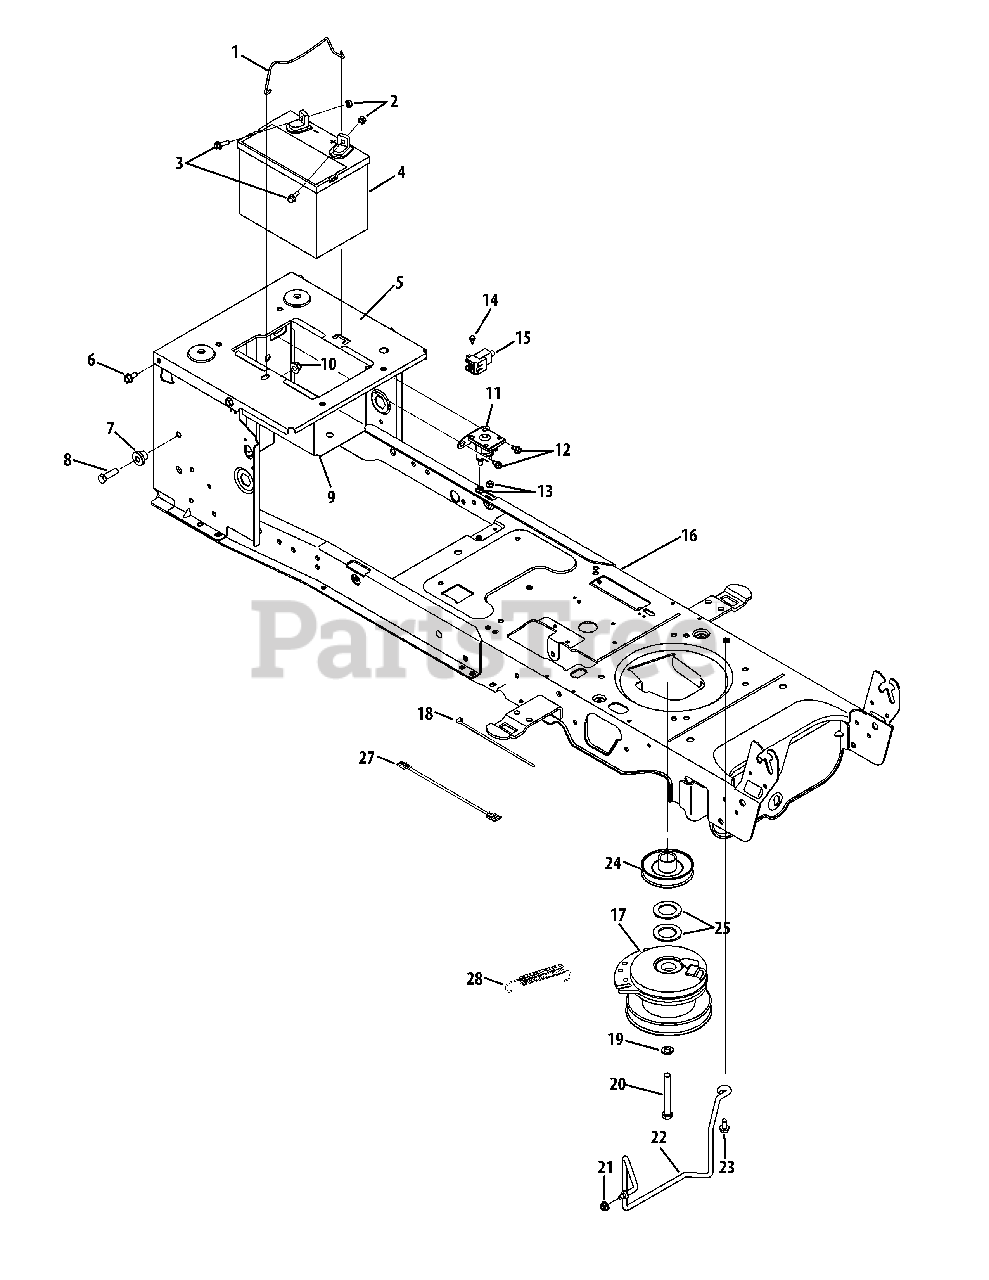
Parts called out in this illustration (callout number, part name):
1	Battery Hold Down Rod
2	Sems Hex Nut 1/4-20
3	Hex Hd. Flg. Scr. 1/4-20 x .75 Gr. 5
4	Battery
5	Seat Frame Bracket
6	SCREW 5/16-18 x .750
7	Shoulder Spacer .38 x 1.0 x .70
8	Hex Bolt 3/8-16 x 1.25
9	Battery Tray
10	Flange Lock-Nut 3/8-16 Gr. F Ny lon
11	Solenoid
12	Hex Wash HD Tapp Scr 1/4-20 x .375
13	Hex L-Flanged Nut 1/4-20 Gr. F Nylon
14	Shoulder Screw #10-32 x .50
15	Switch, Interlock
16	Lower Frame Ass'y
17	Electric PTO Clutch (50" deck)
17	Electric PTO Clutch (54" deck)
18	Cable Tie
19	Flat Washer .450 x 1.25 x .164
20	Hex Screw 7/16-20 x 3.5 Gr. 5
21	Flange Locknut 5/16-18 Gr. F, Nylon
22	Keeper Rod (50" & 54")
23	SCREW 5/16-18 x .750
24	Engine Pulley
25	Flat Washer 1.03 ID x 1.64 OD x .095
26	Ext. Spring .5 OD x 5.52" Lg. (50" & 54")
27	Jumper Clutch Harness
28	Extension Spring
